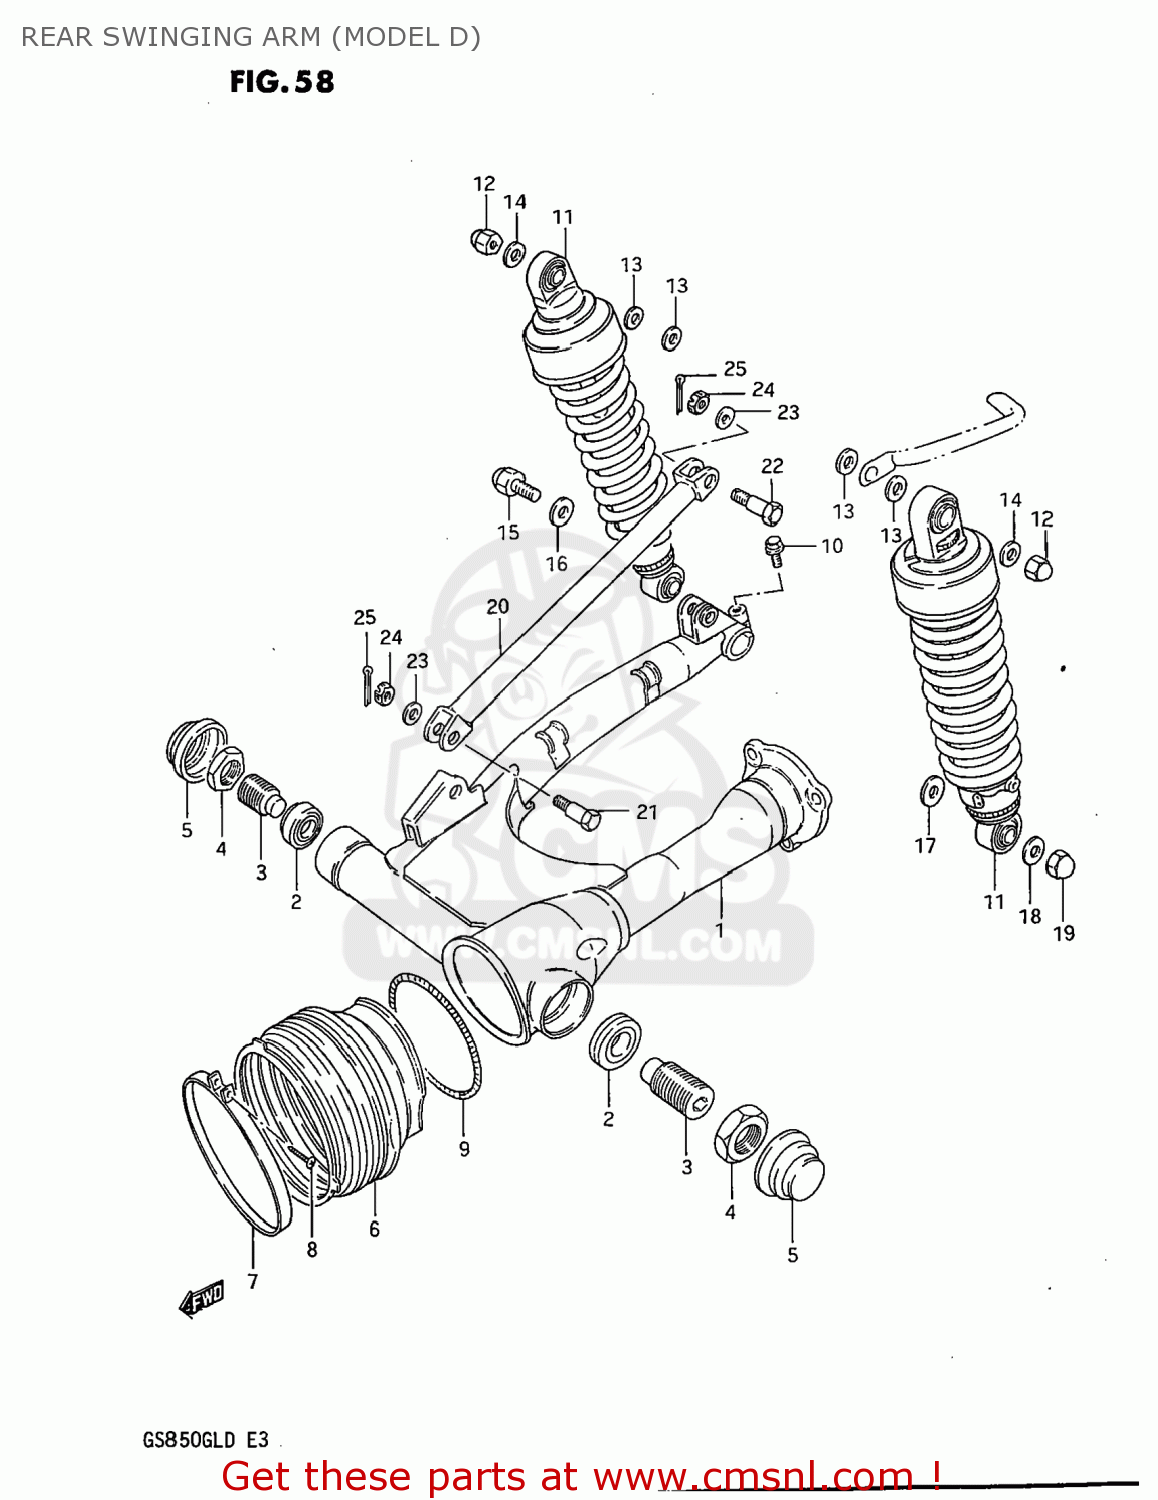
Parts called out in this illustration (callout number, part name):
1	SWING ARM SET,REAR (B
2	BEARING(17X40X13.25)
3	BOLT,REAR SWING ARM PIVOT
4	NUT
5	CAP,REAR SWING ARM PIVOT
6	BOOT,PROPELLER SHAFT
7	CLAMP
8	SCREW 4X25
9	SPRING,PROPELLER SHAFT
10	BOLT
11	ABSORBER ASSEMBLY,REAR SHOCK
12	NUT
13	WASHER
14	WASHER
15	BOLT 12X33
16	WASHER (12.5X24X1.6)
17	WASHER
18	WASHER
19	NUT, LOWER LH
20	TORQUE LINK,REAR
21	BOLT
22	BOLT(10X39)
23	WASHER
24	NUT
25	PIN 20X20
